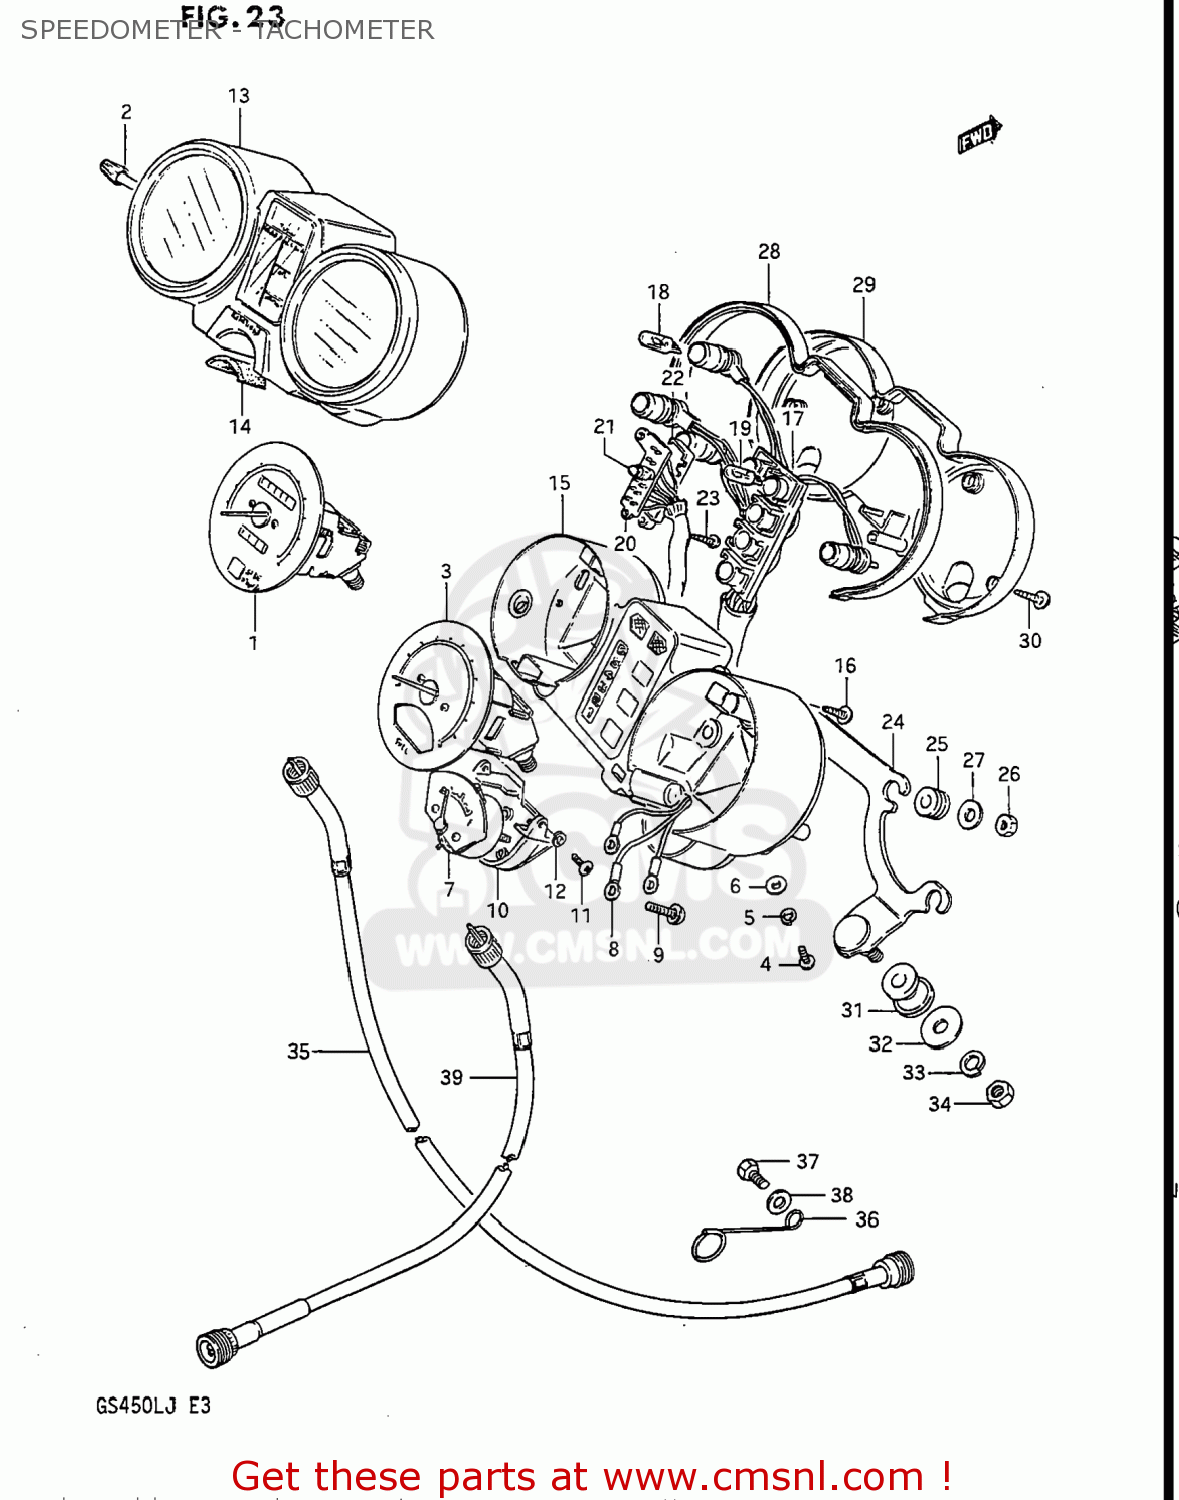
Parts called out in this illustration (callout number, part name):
1	SPEEDOMETER
2	KNOB
3	TACHOMETER
4	SCREW 4X10
5	WASHER 4MM
6	WASHER,LOCK 4M
7	METER,FUEL
8	WIRE,FUEL METER LEAD
9	SCREW(3X22)
10	BRACKET,FUEL METER
11	SCREW
12	LOCK WASHER
13	HOOD,METER
14	SEAL,IGNITION SWITCH
15	CASE,METER,INNER
16	SCREW
17	SOCKET,METER
18	BULB(12V3.4W,T10)
19	BULB(12V1.7W,T10,WB121)
20	SOCKET,GEAR INDICATOR
21	BULB(14V1.12W,BQ041-32503B)
22	COVER,INDICATOR,LOWER
23	SCREW
24	BRACKET,COMBINATION METER
25	CUSHION,METER
26	NUT
27	WASHER (5.5X16X1.2)
28	COVER,METER,UNDER
29	COVER,LWR
30	SCREW
31	CUSHION,METER BRACKET
32	WASHER (8.5X20X1.6)
33	WASHER,LOCK,8.
34	NUT
35	CABLE ASSEMBLY,SPEEDOMETER
36	CLAMP,SPEEDOMETER CABLE
37	BOLT
38	WASHER
39	CABLE ASSEMBLY,TACHOMETER
